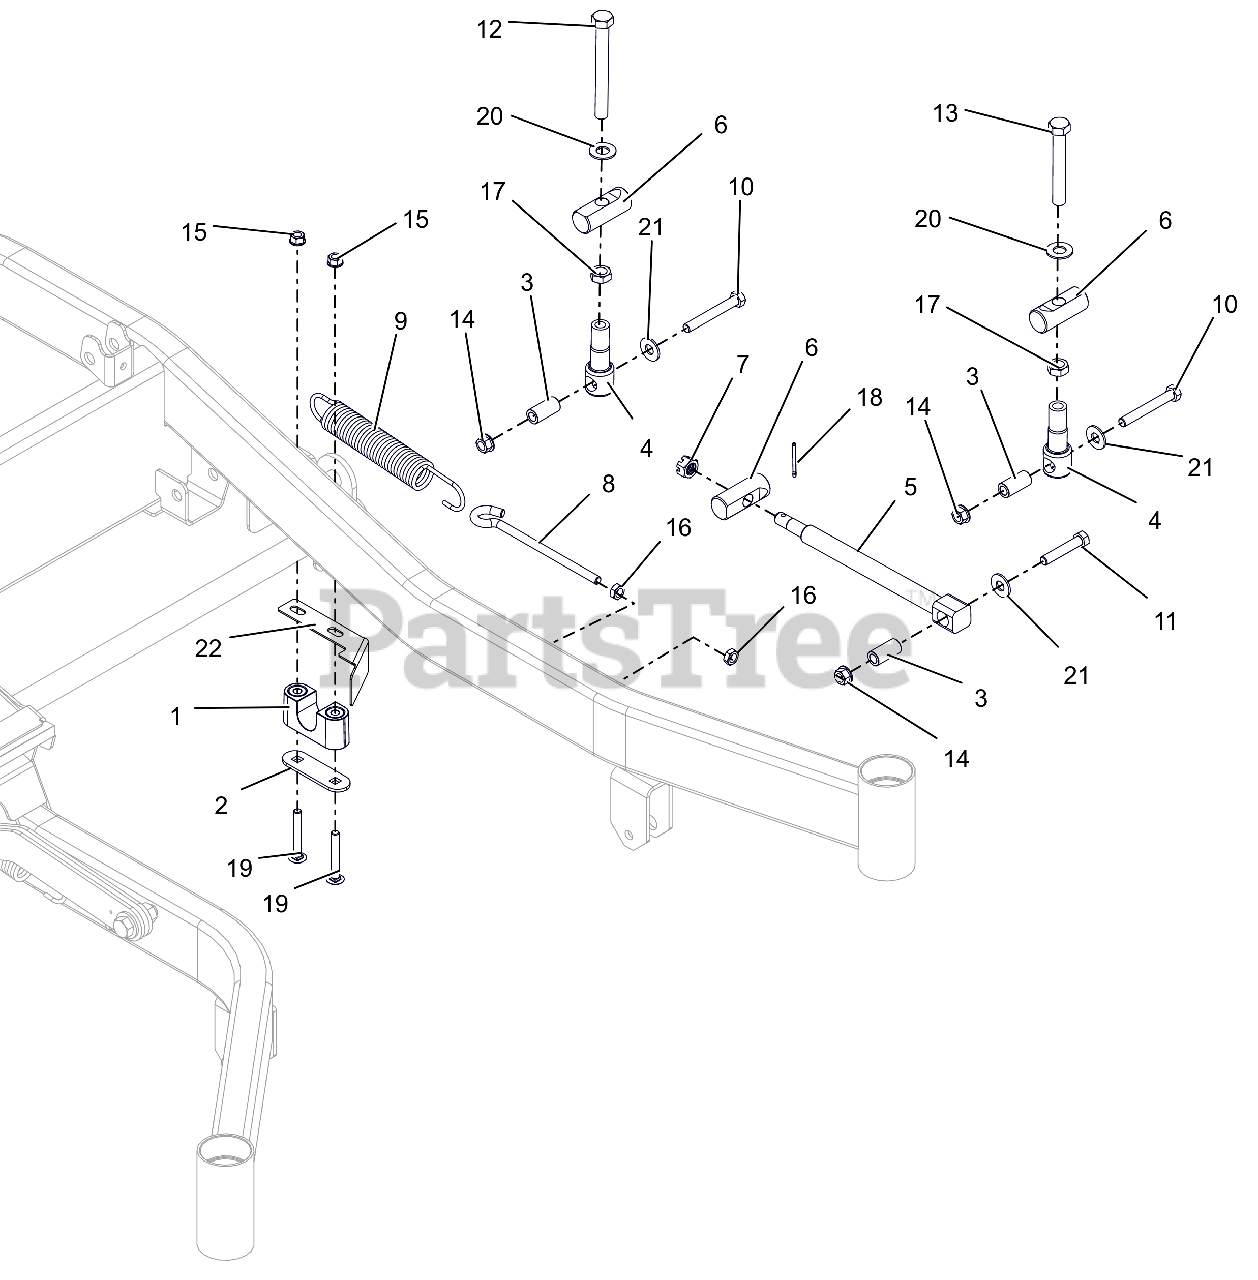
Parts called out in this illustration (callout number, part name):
1	ASM-BUSHING, DECK LIFT
2	PLATE, BEARING SUPPORT
3	SPACER, DECK LEVELING
4	LINK, DECK LIFT FORMED
5	DRAG,LINK-HD
6	PIN, DECK LIFT
7	NUT-SL .50-13
8	BOLT,.38-16 X 5.25-.62 DIA EYE
9	SG-TENS .162X1.25X8.25 WLD 25
10	BLT, HEX .38-16X2.75 G8 ZCC
11	BLT,HEX .38-16X2.00 G5 ZCC
12	BLT, HEX .50-13X4.50F G8 ZCC
13	BLT, HEX .50-13X3.50F G5 ZCC
14	NUT-LK-TOP-FLG .38-16 ZC120
15	NUT,LK-CTR-FLG .31-18 GF ZCC
16	NUT-JAM .375-16 G2 ZCC
17	NUT-JAM .500-13 G2 ZCC
18	PIN,CTR.12X1.25EXTPRSQCT ZC120
19	BLT, RHSSN.31-18X2.25 G5 ZCC
20	WSHR, FLT .557X1.040X.102 ZCC
21	WSHR,FLT .438X1.00X.083 ZCC
22	GUARD, STOP CE 60 (BLACK)
